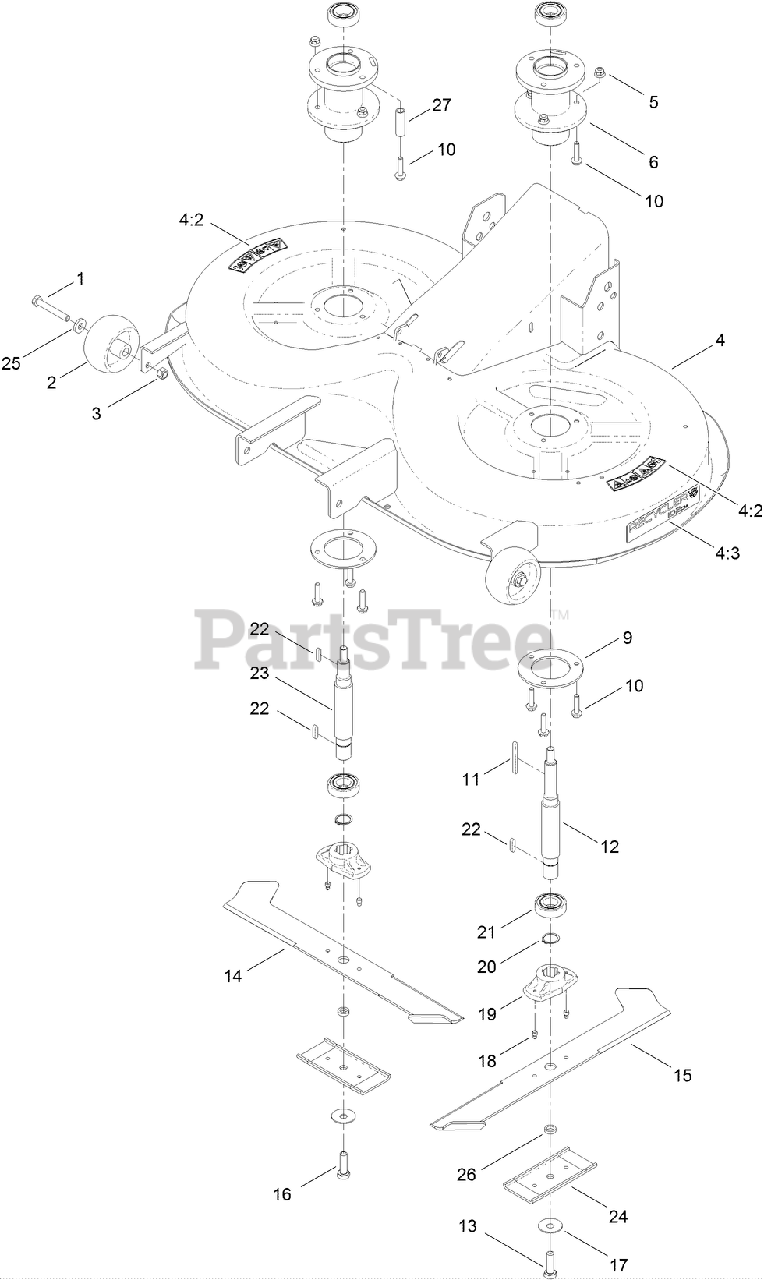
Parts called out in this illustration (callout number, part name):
1	SCREW-HH
2	WHEEL-GAUGE
3	NUT-LOCK, NI
4	DECK-ASSEMBLY, COMPLETE
4:2	DECAL-DANGER
4:3	DECAL-RECYCLER
5	NUT-LOCK, HHF
6	HOUSING-SPINDLE
9	SUPPORT-RING
10	BOLT-HHF
12	Shaft-Blade, LEFT
13	BOLT-HH
14	BLADE-RH
15	BLADE-LH
16	BOLT-BLADE, HH
17	WASHER-BLADE
18	PIN-SHEAR, GROOVED
19	Adapter-Blade
20	RING-LOCKING
22	KEY-SQUARE
23	Shaft-BLADE, Right
24	STIFFENER-BLADE
25	WASHER-FLAT
26	Spacer
27	SPACER
